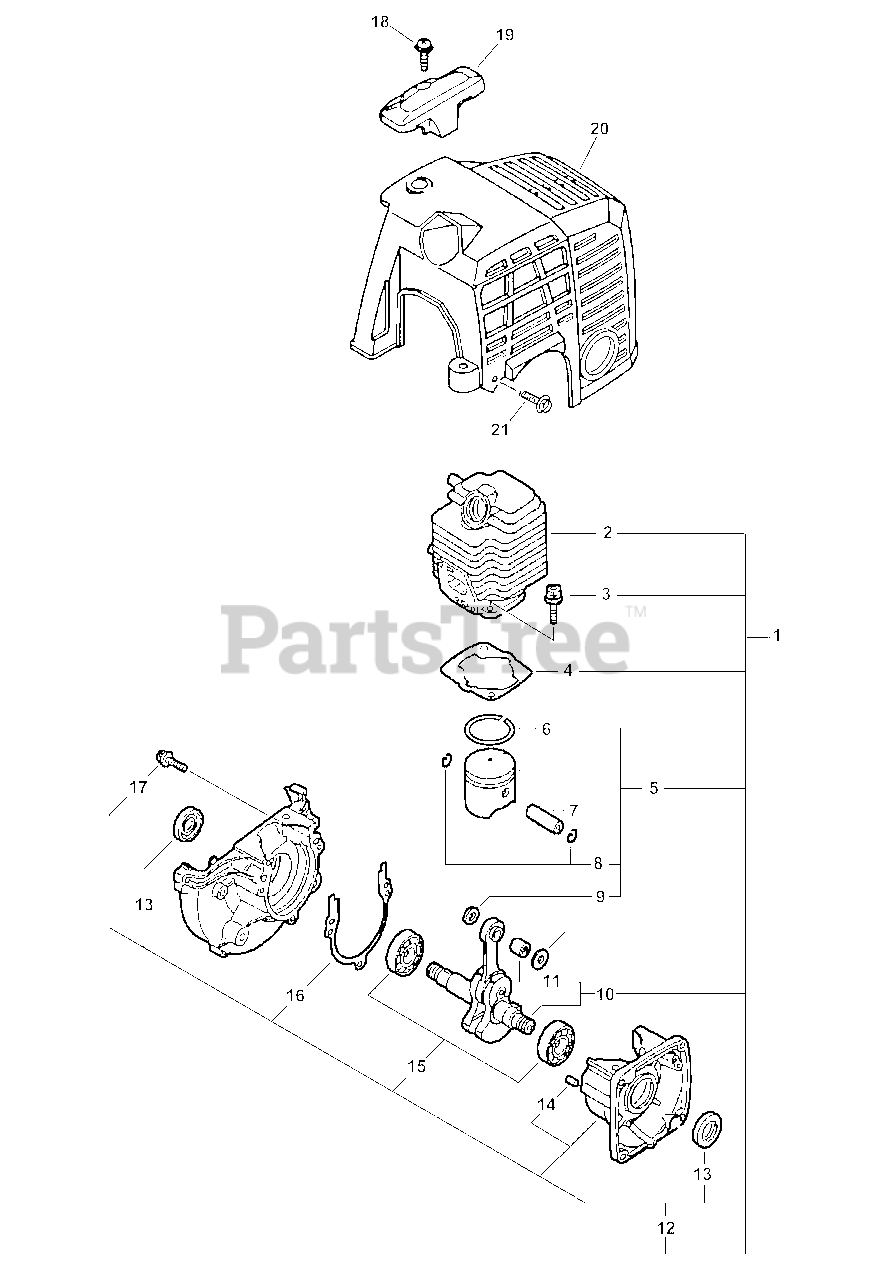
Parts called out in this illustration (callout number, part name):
1	SHORT BLOCK ES-2100;PB-2100
2	CYLINDER
3	BOLT 5×22
4	GASKET, CYLINDER
5	PISTON KIT
6	RING, PISTON
7	PIN, PISTON 8
8	RING, SNAP
9	WASHER, THRUST
10	CRANKSHAFT ASSY
11	BEARING, NEEDLE
12	CRANKCASE KIT
13	SEAL, OIL 12
14	PIN, LOCATING 4
15	BEARING, BALL - 6201 C3
16	GASKET, CRANKCASE
17	BOLT 5×28
18	SCREW 5×16
19	GUARD, TOP
20	COVER, ENGINE
21	BOLT 4×16
